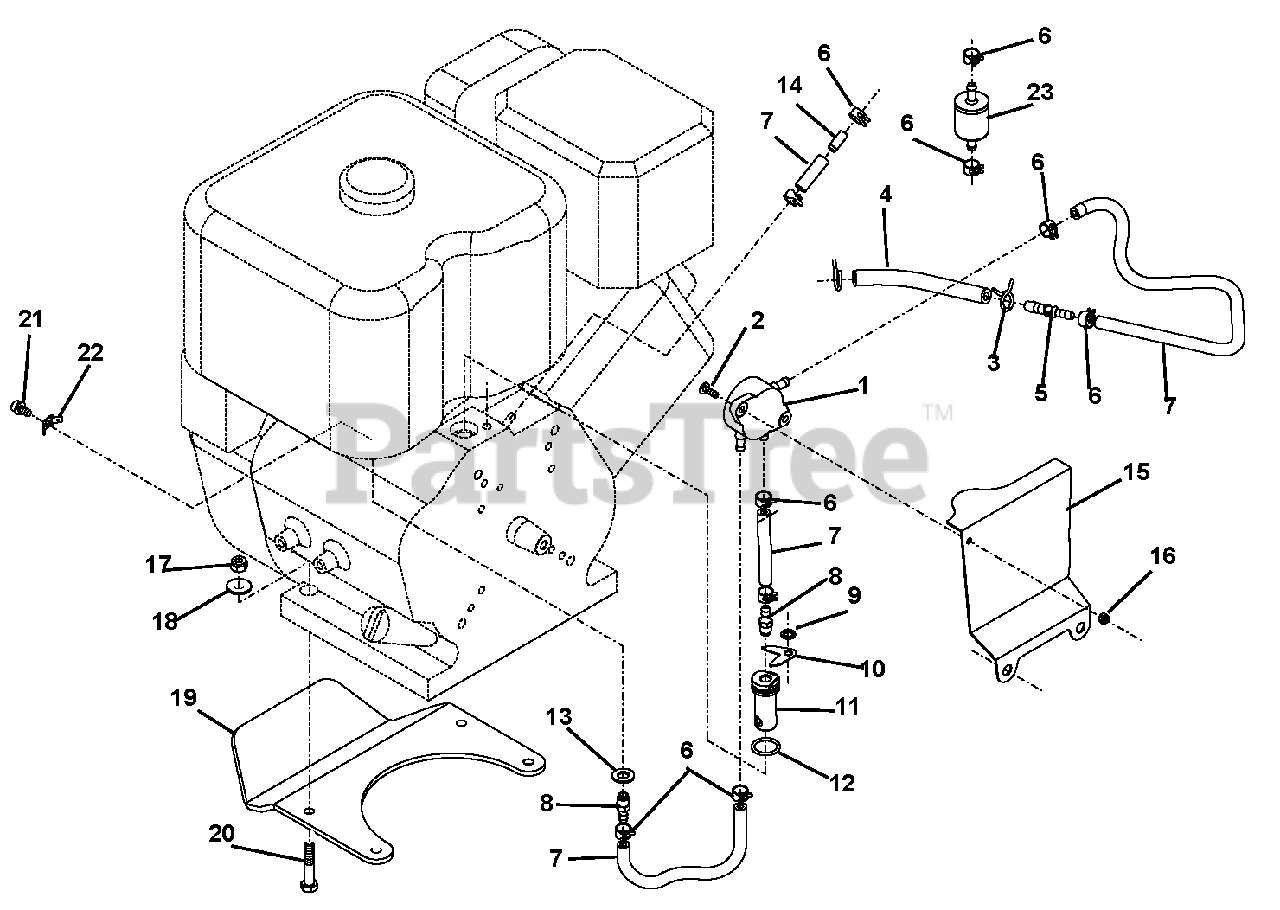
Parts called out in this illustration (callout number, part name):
1	Pump, Fuel
2	Screw, M5 x 16
3	Hose Clamp
4	Pipe 14 x 8
5	Nipple, Reduction
8	Connector
9	Washer, Form Z 8.2/12.7 x 1.4
10	Washer, Lock
12	O-Ring, 20.63 x 2.62
13	Washer, 10.5 x 25 x 2
14	Straight Pin
15	Pipe, Safety
16	Nut, Lock M5
17	Nut, Lock M8
18	Washer, 8.2/22.25 x 1.9
19	Guard Plate
20	Bolt, Hex M8 x 45
21	Bolt, Hex M6 x 30
22	Shell, Cable
23	Gasoline Filter
